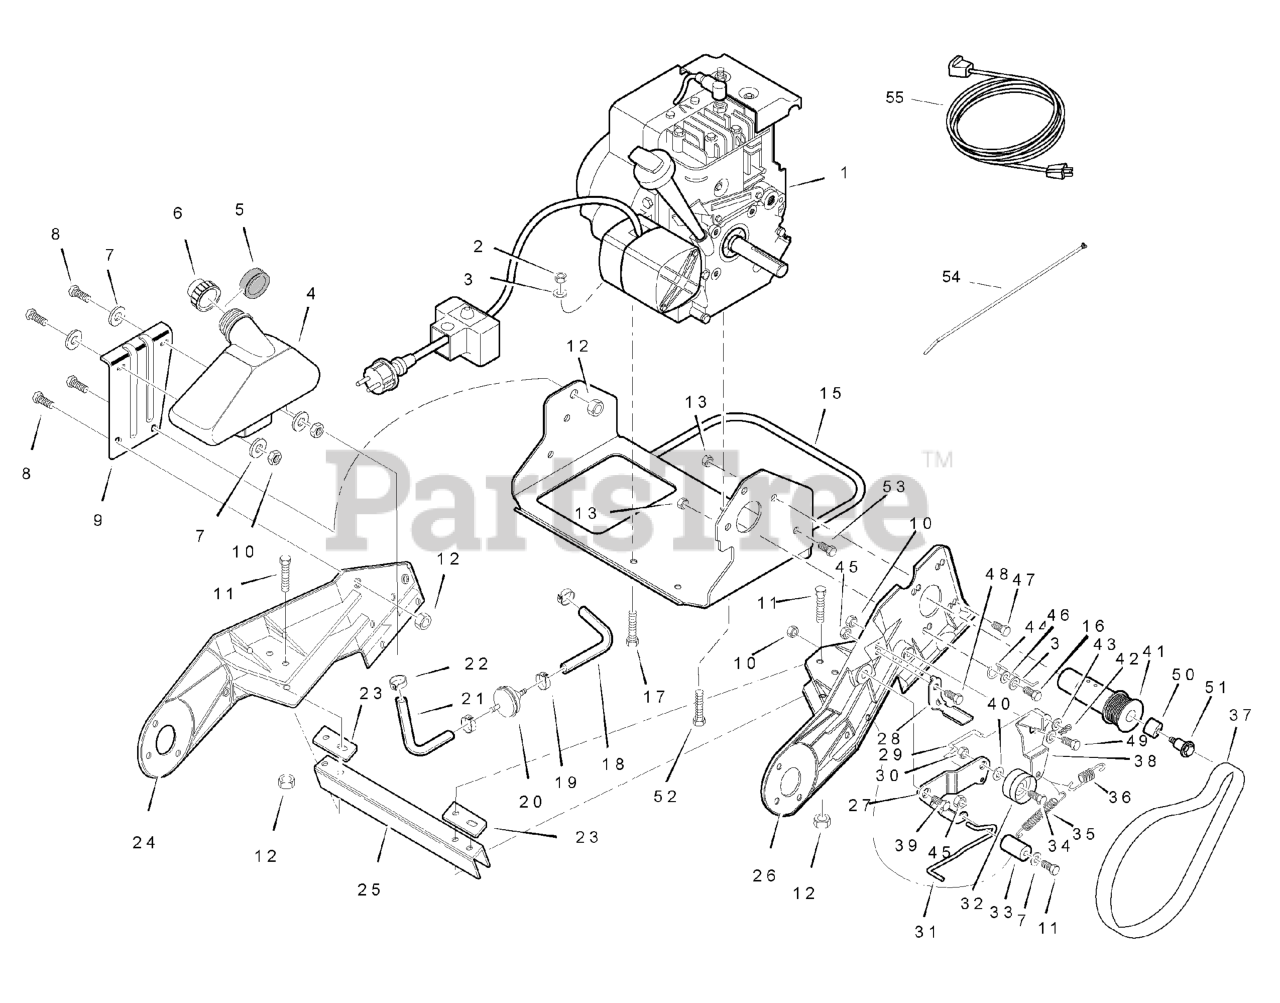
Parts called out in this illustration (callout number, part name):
1	ENGINE
2	NUT, 5/16-18
3	WASHER, SPLIT LOCK .31 X .58 X .08
4	TANK, FUEL 1.5QT
5	RING, FOAM FUEL TANK
6	CAP, FUEL
7	WASHER, FLAT
8	SCREW, 1/4-20 X 0.75
9	BRACKET, FUEL TANK
10	NUT, 8-32 HEX KEPS
11	SCREW, 1/4-20 X 2.00
12	NUT, 1/4-20 HEX
13	NUT, 5/16-18 HEX CONTROL LOCK
15	CRADLE, WELDMENT
16	BOLT, 5/16-18 X 0.75
17	BOLT, ENGINE MOUNT
18	HOSE, FUEL 12 INCHES
19	CLAMP, FUEL LINE
20	FILTER-FUEL
21	HOSE, FUEL 12 INCHES
22	CLAMP, HOSE SCREW
23	PLATE, BOLTING SUPPORT
24	FRAME, RIGHT HAND
25	CHANNEL, FRAME SUPPORT
26	FRAME, LEFT HAND
27	LF ARM, IDLER BRACKET
28	BRAKE PAD
29	ROD, CLUTCH LINKAGE
30	NUT, 3/8-16 JAM CONTROL LOCK
31	WIRE, BRAKE
32	PULLEY, IDLER
33	ROLLER, PINCH
34	SCREW, 3/8-16 X 1.50
35	SPRING, EXTENSION .38 OD X .039 X 2.50
36	SPRING, EXTENSION .75 OD X .069 X 2.00
38	ARM, IDLER PIVOT
39	BOLT SHD .500 X .177 X .31
40	WASHER, FLAT
41	PULLEY, ENGINE
42	PIN, COTTER
43	WASHER, FLAT #8
44	GUIDE, BELT
45	NUT, 1/4-20
46	WASHER
47	SCREW 5/16-18 X 0.63 WAHHC
48	SCREW, 1/4-20 X 0.63
49	SCREW, 8-32 X 3.00
50	SPACER, DRIVE PULLEY
51	BOLT, ENGINE PULLY
52	BOLT, 5/16-18 X 0.865
53	SCREW .25-20 X .062 WAHHTA
54	TIE, CABLE
55	CORD, ELECTRIC 10FT. 220V
